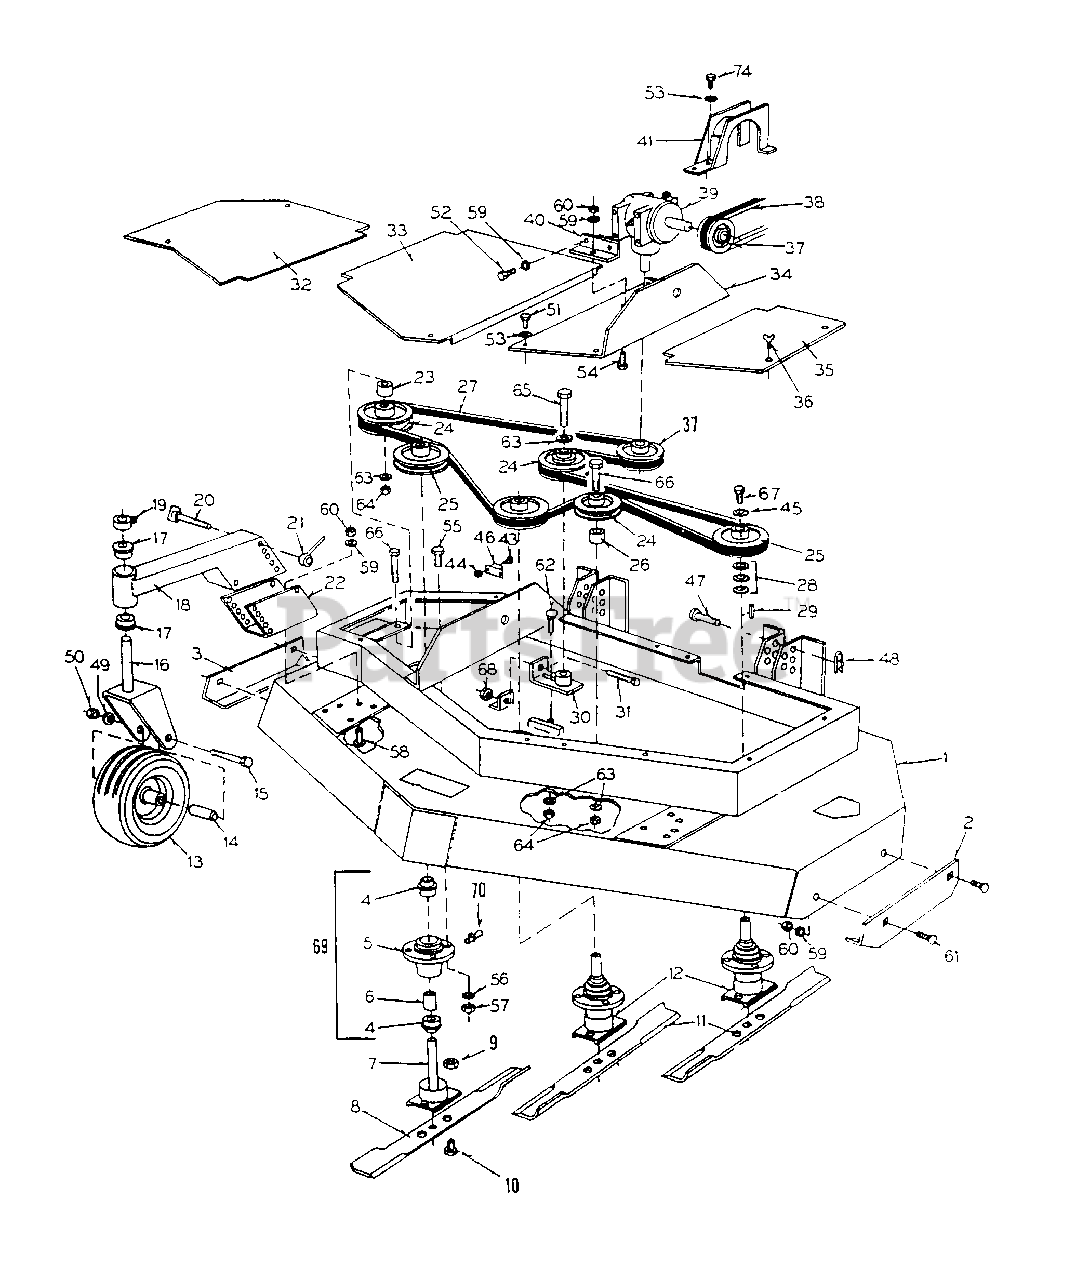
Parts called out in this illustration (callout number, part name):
1	DECK - rear discharge 52"
2	SHOE - skid L.H.
3	SHOE - skid R.H.
4	BEARING - spindle 7/8"
5	HOUSING - spindle
6	SPACER - spindle
7	SHAFT - spindle L.H. rotation
8	BLADE - L.H. rotation
9	NUT - 3/8" - 16 lock
10	BOLT - 3/8" - 16 x 1
11	BLADE - R.H. rotation
12	SHAFT - spindle
14	AXLE - gauge wheel
15	BOLT - 1/2" - 13 x 6-1/2"
16	FORK - gauge wheel
18	MOUNT - gauge wheel
19	COLLAR - set 1"
20	BOLT - wing 3/8" - 16 x 4-1/2"
21	NUT - gauge wheel handle 3/8" - 16
22	BRACKET - gauge wheel mount
23	SPACER - idler pulley
24	PULLEY - idler 5"
25	PULLEY - spindle 4-1/2"
26	SPACER - idler pulley
28	WASHER - spacer
29	KEY - 3/16" x 3/16" x 1"
30	TIGHTENER - belt
31	BOLT - 1/4" - 20 x 4"
33	COVER - center
34	MOUNT - gear box
36	SCREW - thumb 1/4" - 20 x 1/2"
37	PULLEY - gear box input
38	BELT - drive (1800C)
39	GEAR BOX - angle drive
40	ANGLE - gear box mount
43	SCREW - #10 - 32 x 1/2"
44	NUT - lock #10 - 32
45	WASHER - spindle
46	BREAKER - circuit 10 amp.
47	PIN - clevis 1/2" x 1-1/2"
48	PIN - cotter, hair
49	LOCKWASHER - 1/2"
50	NUT - 1/2" - 13
51	BOLT - 1/4" - 20 x 3/4"
52	BOLT - 5/16" - 18 x 1"
53	LOCKWASHER - 1/4"
54	BOLT - 5/16" - 18 x 3/4"
55	BOLT - 7/16" - 14 x 1-1/4"
56	LOCKWASHER - 7/16"
57	NUT - 7/16" - 14
58	BOLT - carriage 5/16" - 18 x 1"
59	LOCKWASHER - 5/16"
60	NUT - 5/16"
61	BOLT - carriage 5/16" - 18 x 3/4"
62	BOLT - carriage 3/8" - 16 x 1"
63	LOCKWASHER - 3/8"
64	NUT - 3/8" - 16
65	BOLT - 3/8" - 16 x 1-1/4"
66	BOLT - 3/8" - 16 x 2-1/2
67	BOLT - 3/8" - 24 x 1-1/4"
68	NUT - lock 1/4" - 20
69	HOUSING ASSEMBLY - spindle
70	FITTING - grease 1/4" - 28
